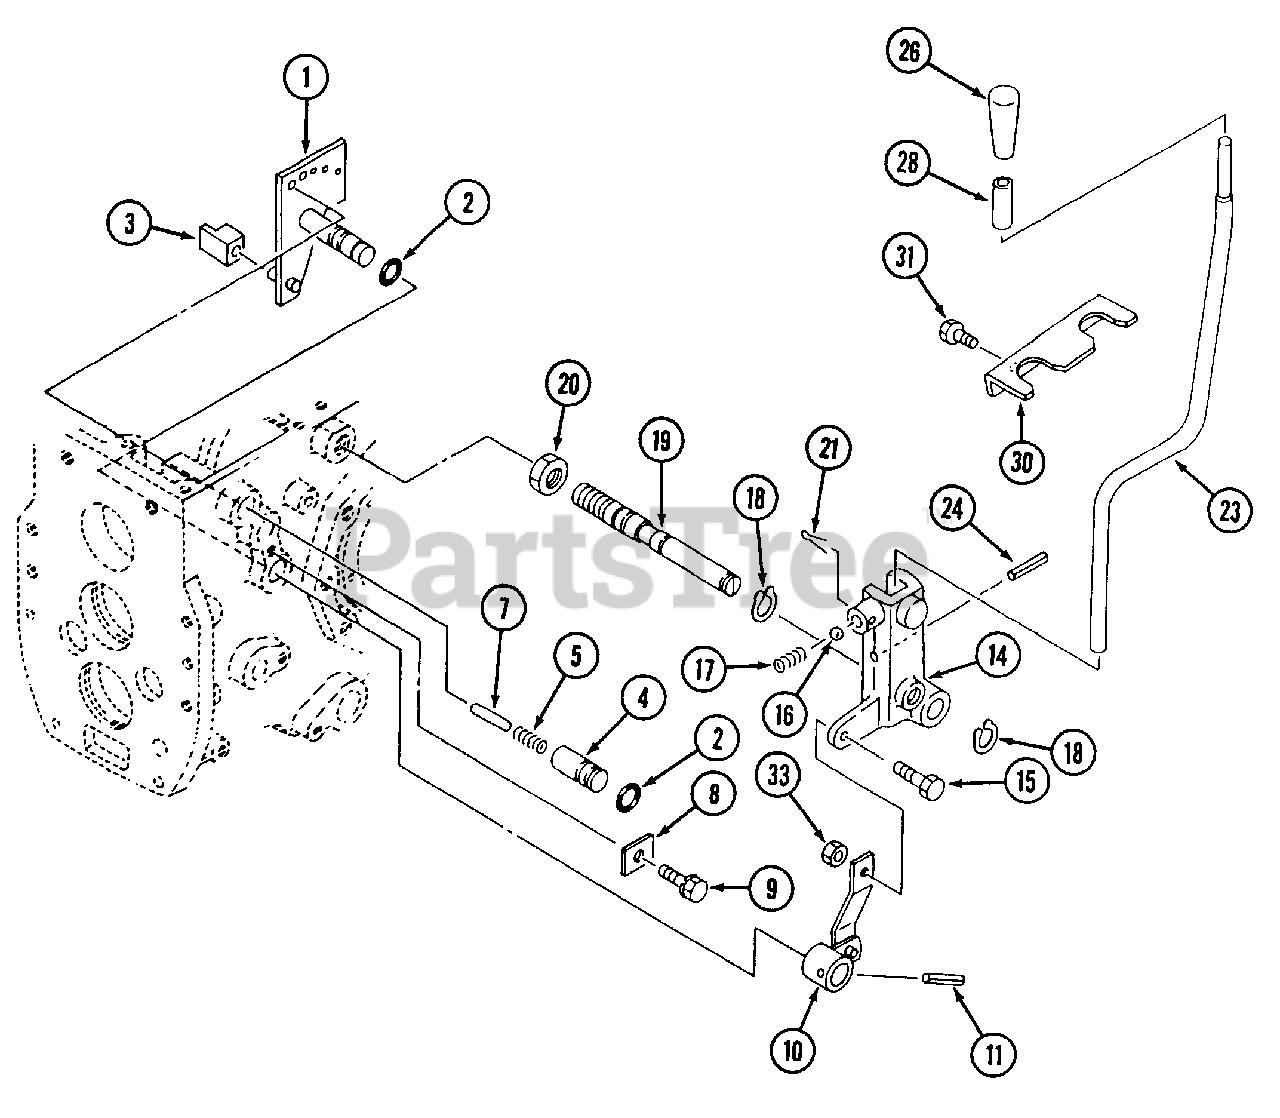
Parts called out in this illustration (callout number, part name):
1	Shifter, Range
14	Bracket, Range
15	Bolt
